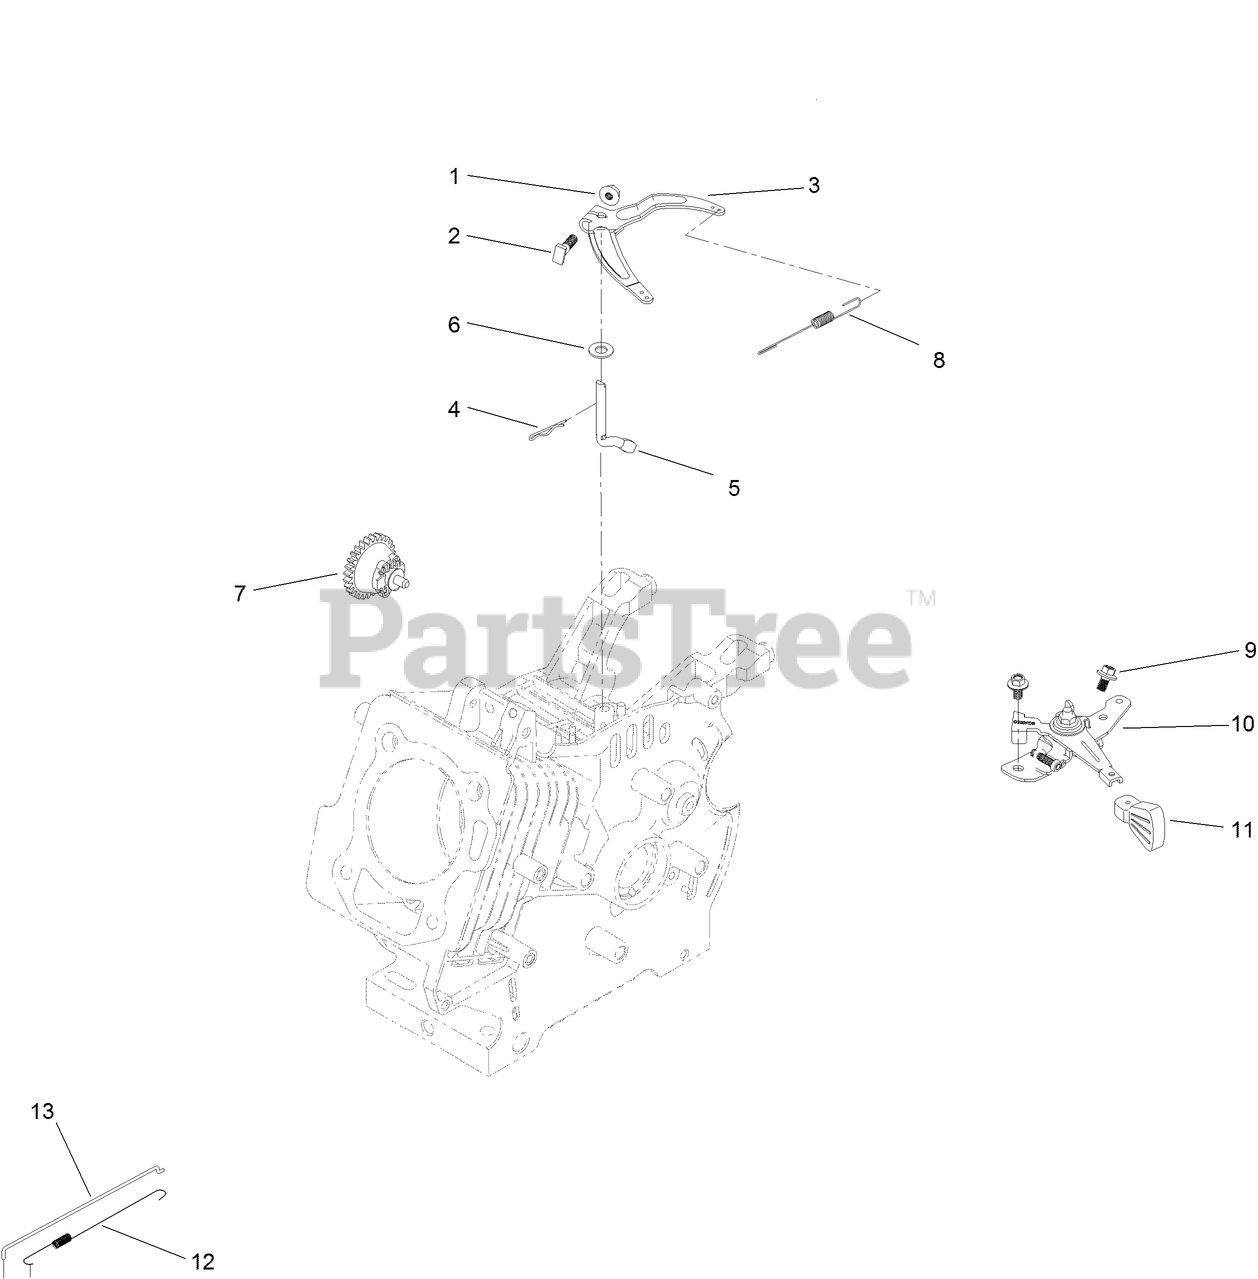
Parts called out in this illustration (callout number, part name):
1	NUT-FLANGE
2	BOLT-ARM, GOVERNOR
3	ARM-GOVERNOR
4	PIN-HAIR
5	SHAFT-GOVERNOR
6	WASHER-PLAIN
7	GOVERNOR GEAR ASM
8	SPRING-GOVERNOR
9	SCREW-HHF
10	THROTTLE CONTROL ASM
11	KNOB-CONTROL, THROTTLE
12	SPRING-RETURN, THROTTLE
13	ROD-GOVERNOR
